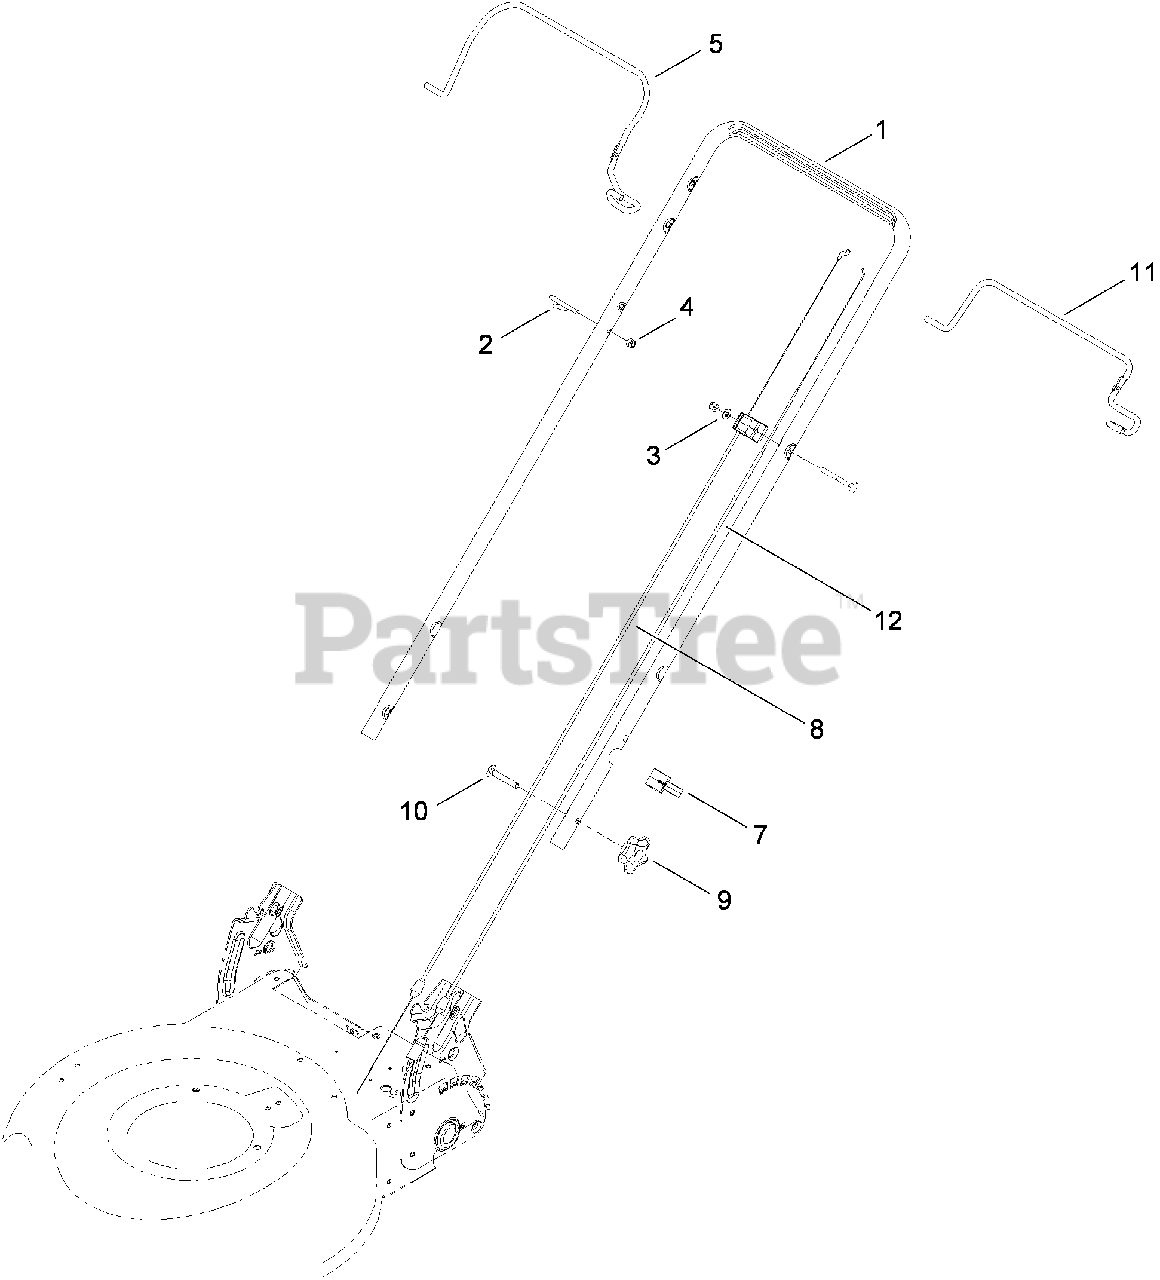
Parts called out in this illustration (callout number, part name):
1	HANDLE
2	GUIDE-ROPE
3	WASHER-FLAT
4	NUT-LOCK, NI
5	BAIL-BRAKE, LB
7	GUIDE-CABLE
8	CABLE-BRAKE
9	KNOB-HANDLE, LOCKING
10	Screw-CARR
11	BAIL-TRACTION, 2-BAIL FLAT
12	CABLE-TRACTION
